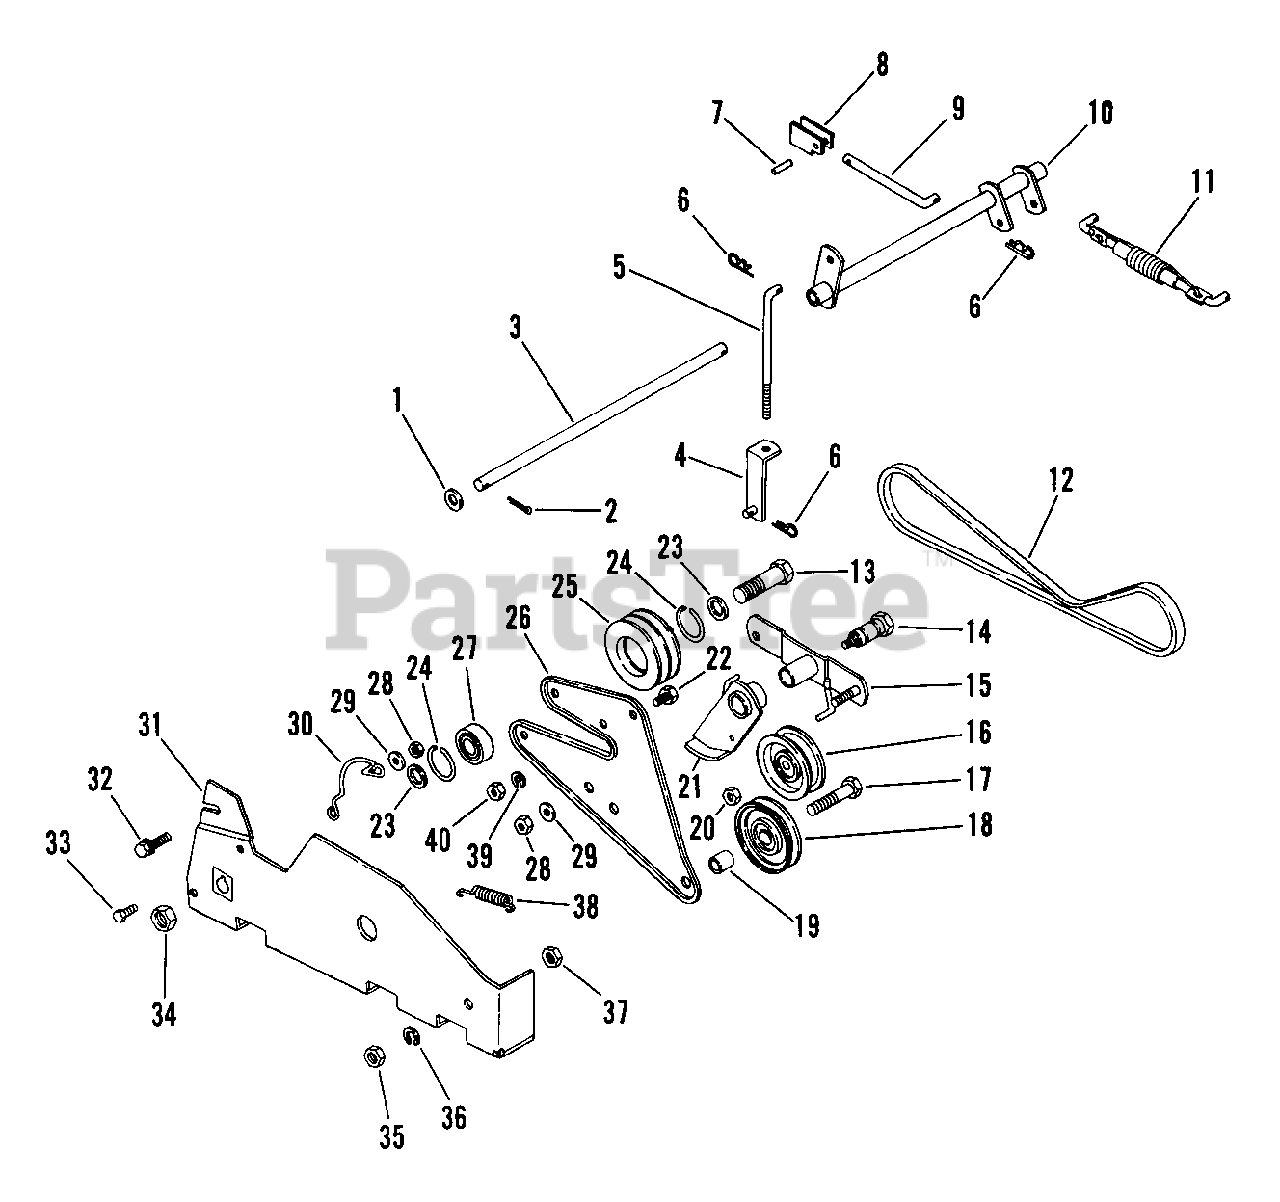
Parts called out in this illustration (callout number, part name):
1	WSHR-FL-STL .531X1.062X.095 PL
2	PIN-COTR .12X1.0 PL
3	PIVOT SHAFT
4	CLUTCH LINK
6	PIN-HAIR INT .08X.18X1.18
7	PIN-ROLL .156X1.00
8	LATCH
9	ROD
10	CLUTCH PIVOT
11	SPRING ASSEMBLY
12	V-BELT, HA-RAW EDGE
13	BLT-HEX .50-20X1.50 GR2
15	IDLER ARM
16	IDLER-FLAT 2.75 X .38 DAYCO
17	BLT-HEX .50-13X2.50 PL GR2 FTH
18	IDLER-V 3.50 X .50 CAPITOL
19	HUB, .50 X .75 X .84
20	NUT-LK-JAM-CTR .375-16 PL
21	BELT BRAKE
22	BLT-HEX .38-16X.75 PL GR5
23	WSHR-FL-STL .754X1.125X.062 PL
24	RG-RTNG-INT 1.781X.062
25	DOUBLE SHEAVE
26	DRIVE MOUNT
27	BRG-BALL .750X1.781X.61
28	NUT-LK .312-18 GR A PL
29	WSHR-FL-STL .38X.875X.083 PL
30	BELT FINGER
31	BELT GUARD
32	SCREW - FLG WIZ LOCK HH PL
33	BLT-HEX .31-18X.75 PL GR2
34	NUT-LK-CTR .75-10 PL
35	NUT-JAM .50-13 PL
36	WSHR-LK .500X.151 HVY PL
37	NUT-LK-CTR .50-13
38	SG-TENS .041X.50X3.25 WLD 3.6
39	WSHR-LK .375X.094 MED PL
40	NUT-HEX .375-16
